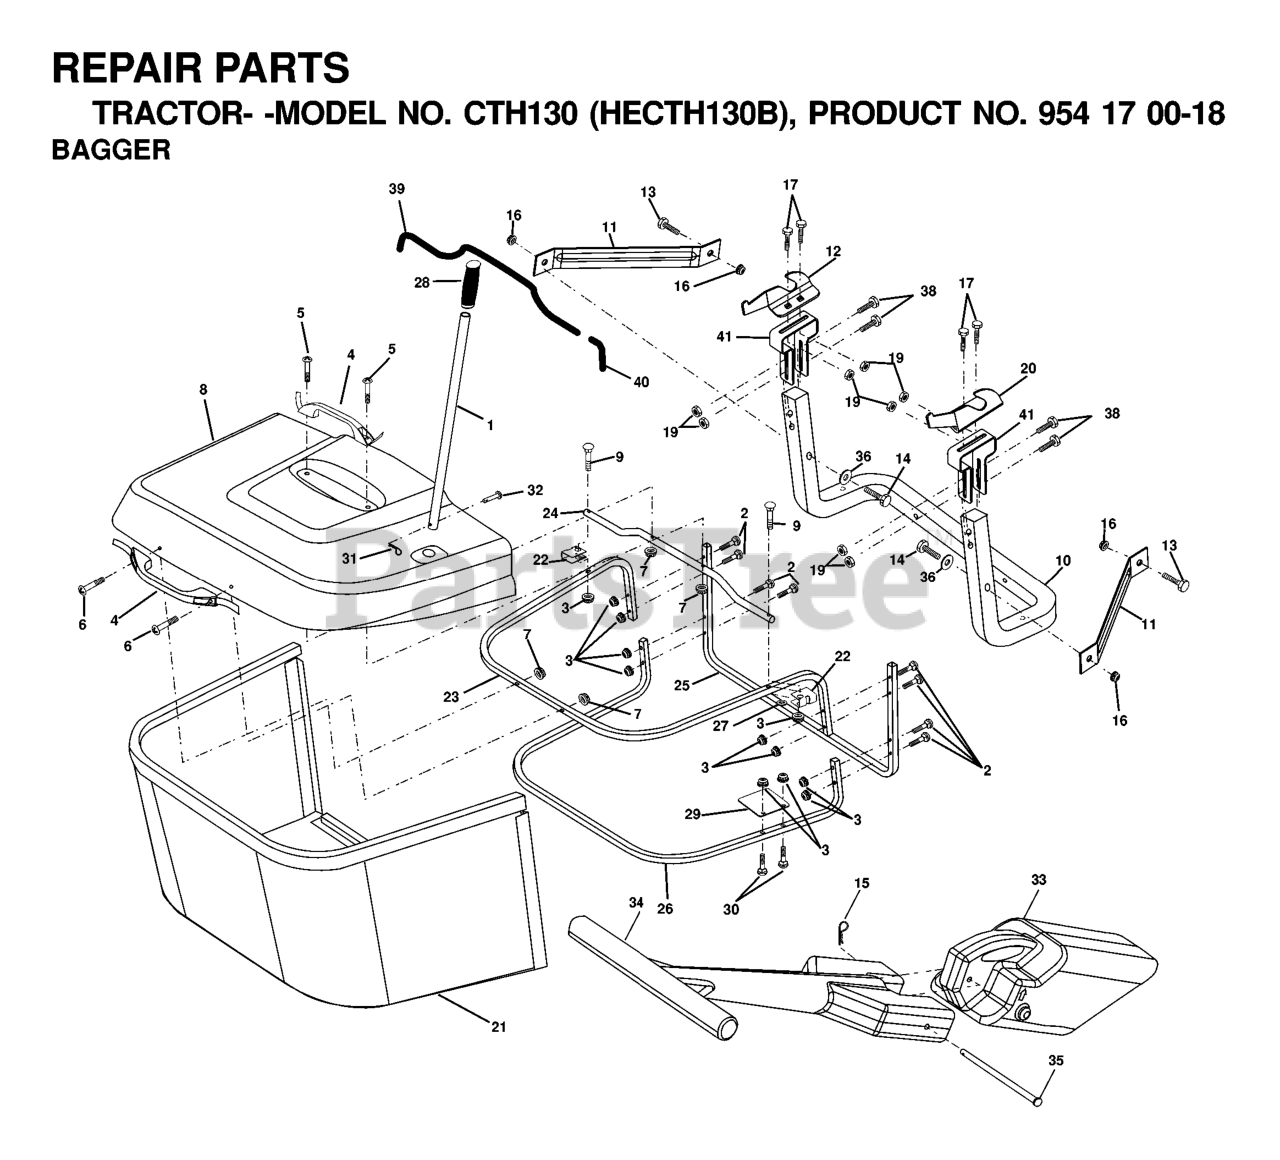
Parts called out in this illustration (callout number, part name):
1	TUBE HANDLE
2	Bolt Carriage 1/4-20 x 2.0 Gr.5
3	NUT T
4	HANDLE.BAGGER.W/LVRS.BLK.CRD
5	SCREW.PAN.HEAD
6	REPL BY 532 75 00-29
8	COVER
9	Bolt Carriage 1/4-20 x 2.25d x Gr.5
10	TUBE
11	BRACKET.SUPPORT.UPPER.BAG.CRD
14	Bolt Hex 3/8-16 x 2-1/2 Gr. 5
15	RETAINER-SPRNG RB
16	NUT LOCK FLG 3/8-16 UNC
17	RP BOLT 5/16-18 X3/4 ZN/YEL GR
18	WASHER M
19	NUT.71038.31-18.HEX.NYLOCK
20	BRACKET
21	BAG
22	BRKT.SIDE.BAG.CRD
23	TUBE.UPPER.BAG.CRD
24	TUBE.PIVOT.BAG.CRD.BLACK
26	TUBE.LOWER.BAG.CRD
28	GRIP.HANDLE.BLACK
30	Bolt Carriage 1/4-20 x 1 Gr.5
31	RETAINER M
32	RIVET,DRILLED
33	PLUG.MULCHER.92 CRD
34	HANDLE.MULCHER.92.CRD (2 2)
36	WASHER
38	BOLT.5/16-18X2.5
39	TRIM
40	TRIM
41	BRKT.VERT.ADJ.BAGGER.CRD
